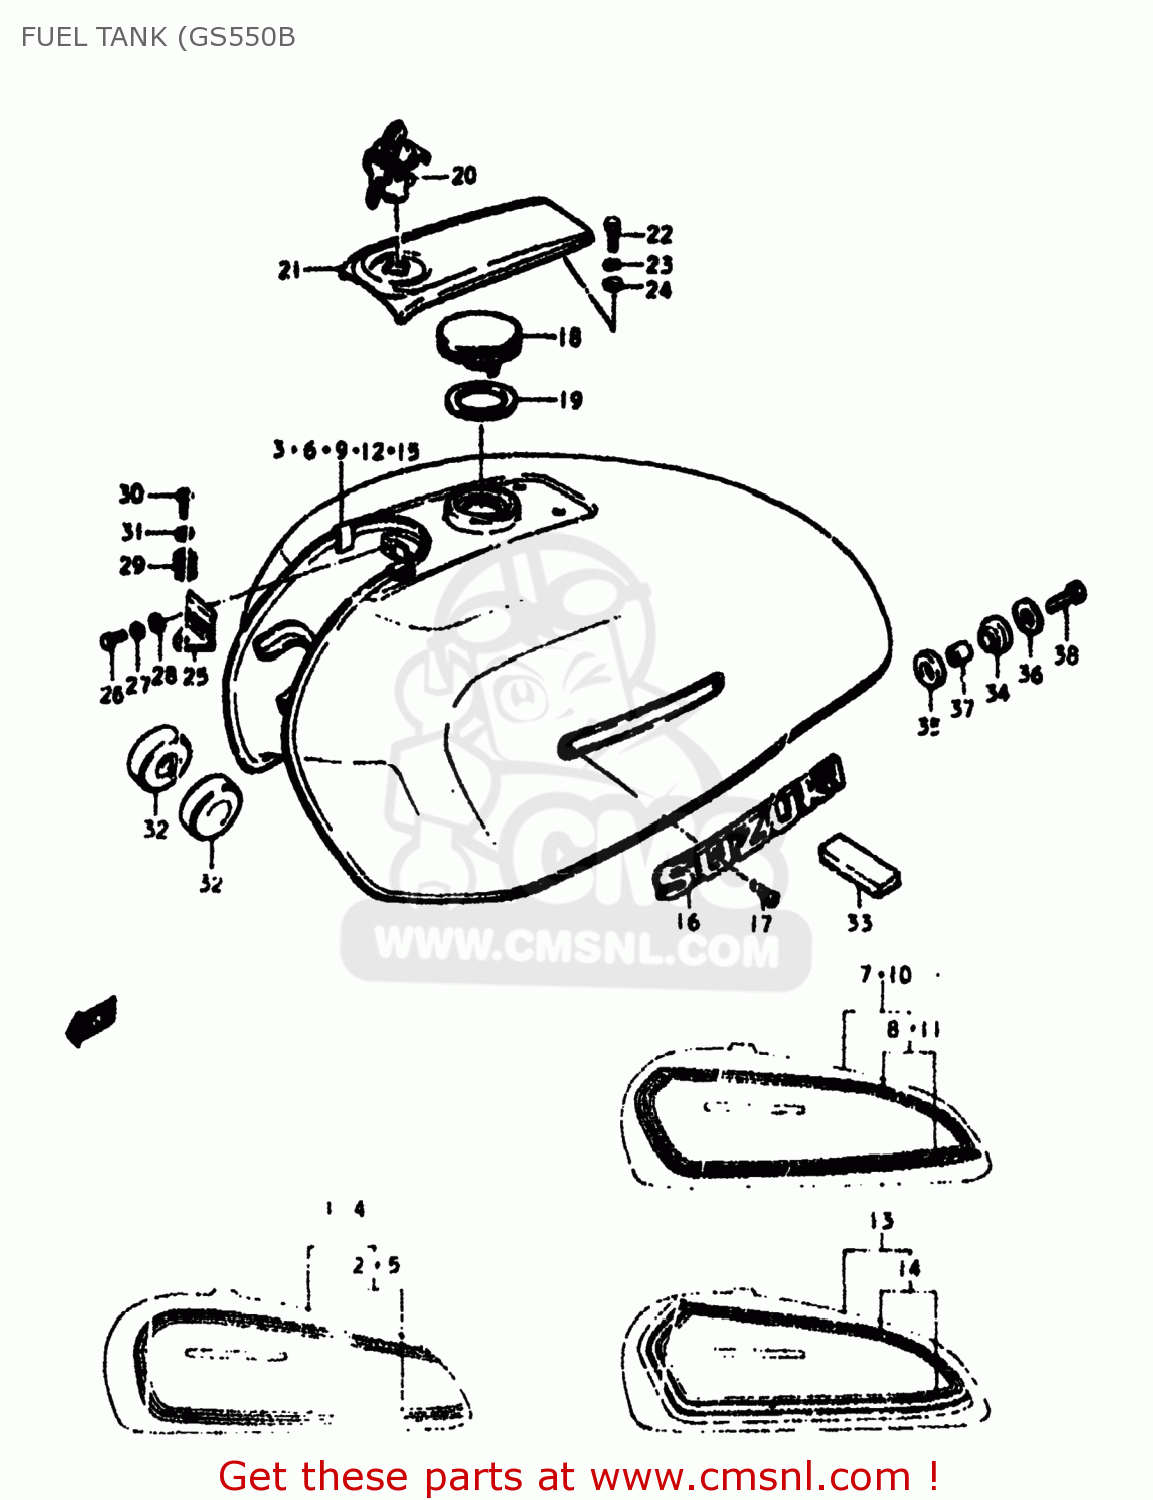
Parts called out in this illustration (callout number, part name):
1	TANK ASSEMBLY,FUEL
3	CUSHION,FUEL TANK FR COVER
4	TANK ASSEMBLY,FUEL
6	CUSHION,FUEL TANK FR COVER
7	TANK ASSEMBLY,FUEL
8	TAPE SET.FUEL T
9	CUSHION,FUEL TANK FR COVER
10	TANK ASSEMBLY,FUEL
11	TAPE SET.FUEL T
12	CUSHION,FUEL TANK FR COVER
13	TANK ASSEMBLY,FUEL
15	CUSHION,FUEL TANK FR COVER
16	EMBLEM,FUEL TANK
17	SCREW
18	CAP,FUEL TANK
19	GASKET (NAS)
20	LOCK,FUEL TANK FR COVER
21	COVER,FUEL TANK
22	BOLT
23	LOCK WASHER
24	WASHER
25	HOLDER,FUEL TANK FRONT COVER
26	BOLT
27	LOCK WASHER
28	WASHER
29	SPRING
30	SCREW
31	LOCK WASHER
32	CUSHION
33	CUSHION
34	CUSHION
35	CUSHION
36	WASHER (8.5X29X1.6)
37	SPACER(8.5X12X19)
38	BOLT (8X30)
